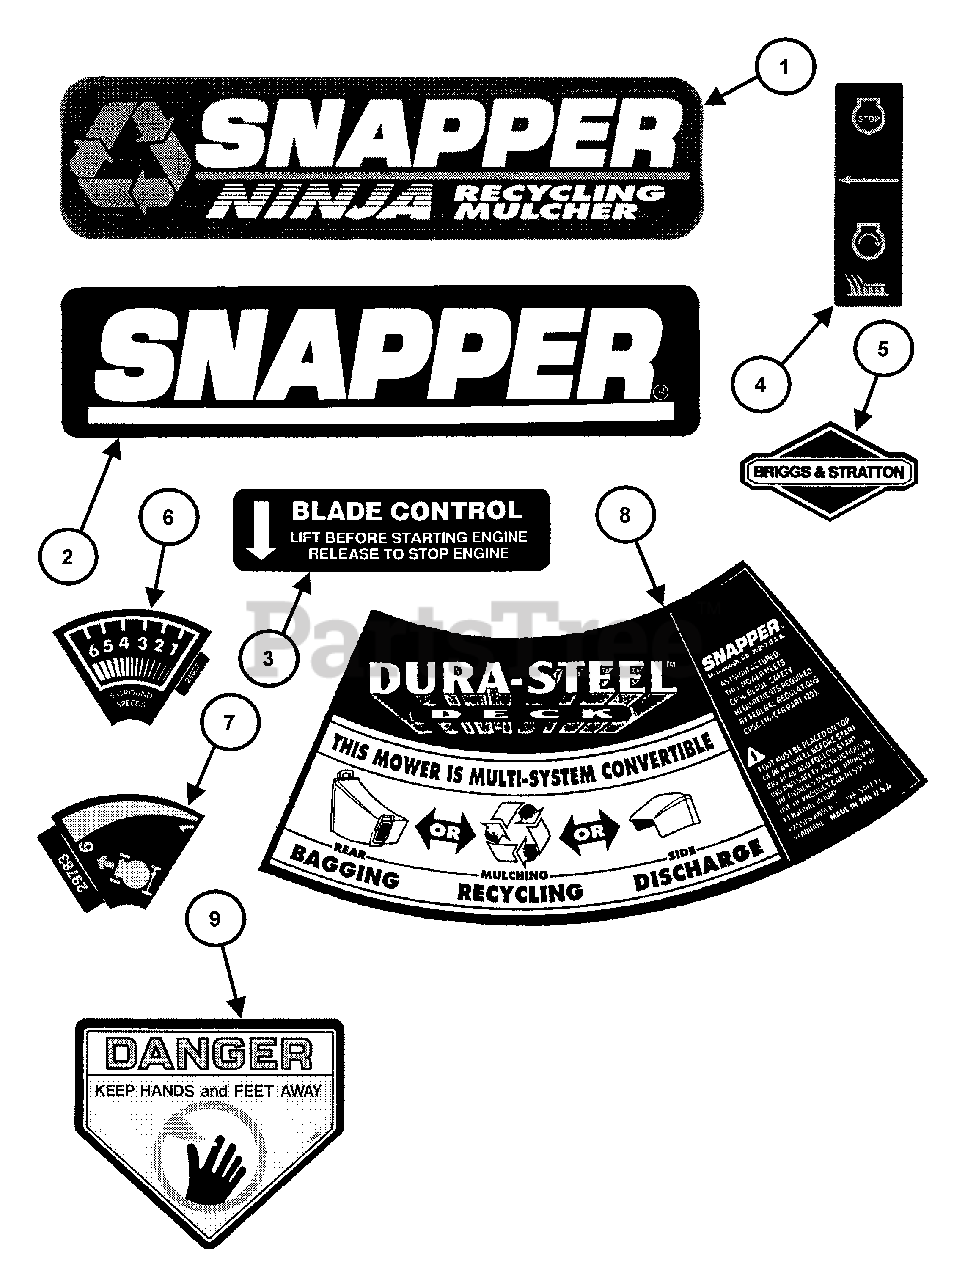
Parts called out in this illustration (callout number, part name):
1	DECAL, Recycling Mulcher (Ninja)
2	DECAL, Snapper
3	DECAL, Blade Control
4	DECAL, Blade Control (European)
5	DECAL, Briggs Logo
6	DECAL, Speed Sector
7	DECAL, Speed Sector (European)
8	DECAL, Convertible
9	DECAL, Danger
